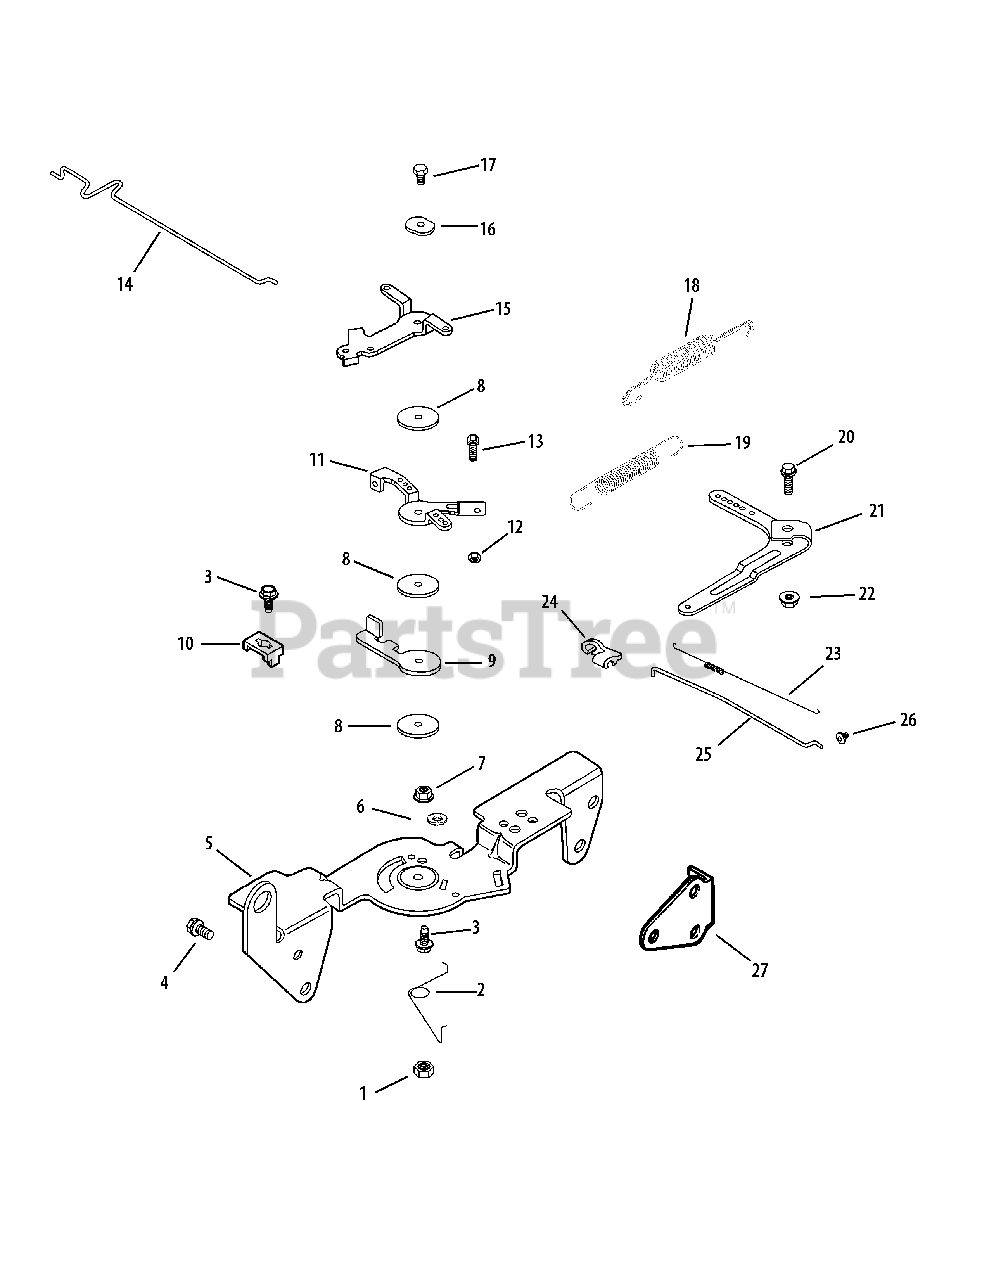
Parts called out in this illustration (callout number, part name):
1	Nut, Lock M5X.8
2	Spring, Choke Return
3	Screw, Flg Thd Frm M5X0.8X16
4	Screw, Flg Thd Frm M6x1.0x16
5	Bracket, Control
6	Washer, Spring Lock 1/4"
7	Nut, Flg M5x.8
8	Washer, Flat 5.5 MM
9	Lever Throttle Actuator
10	Clamp, Cable
11	Lever Throttle Control
13	Screw, Cap M4X0.7X30
14	Linkage, Choke
15	Lever, Choke
16	Washer, Spring 1/4"
17	Screw, Flg Thd Frm M5X0.8X20
18	Spring, Throttle Limiter
19	Spring, Governor
20	Bolt, Rd Hd Sq Neck M6X1.0X25
21	Lever, Governor
22	Nut, Flg M6x1.0
23	Spring, Linkage
24	Bushing, Linkage Retaining
25	Linkage, Throttle
26	Bushing, Throttle Linkage
